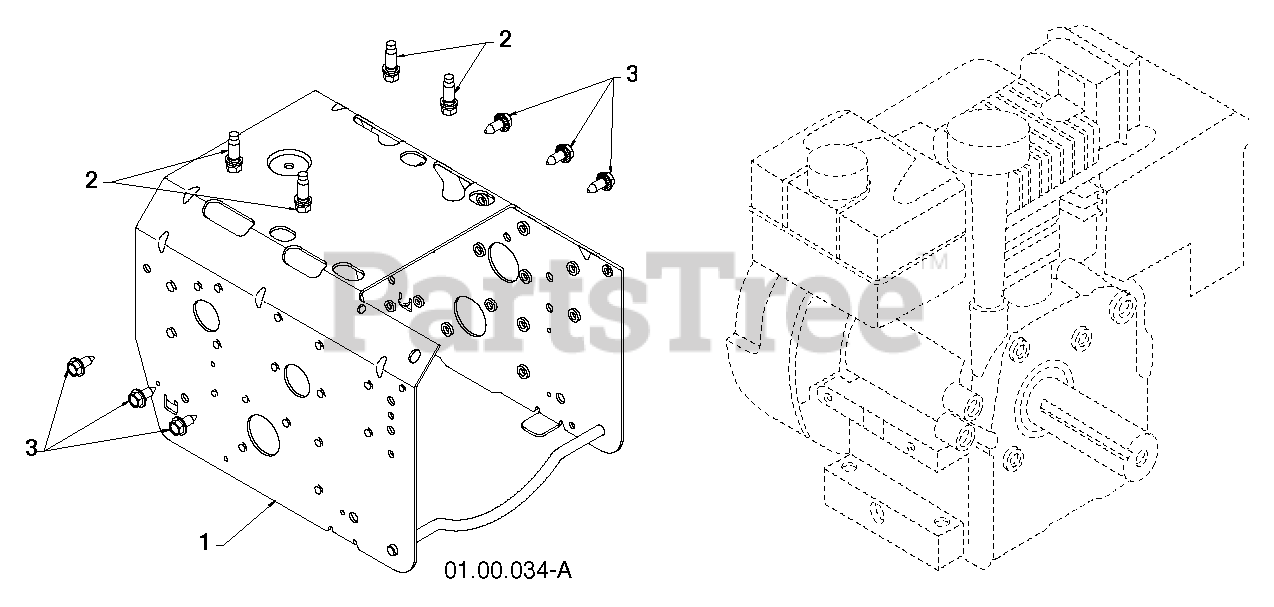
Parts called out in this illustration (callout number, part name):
1	FRAME.WELD.PNT.CHAIN.ORANGE
2	BOLT 3/8-16X1-1/8
3	BOLT.HEX.HD.WASHER.5/16-18X.75
